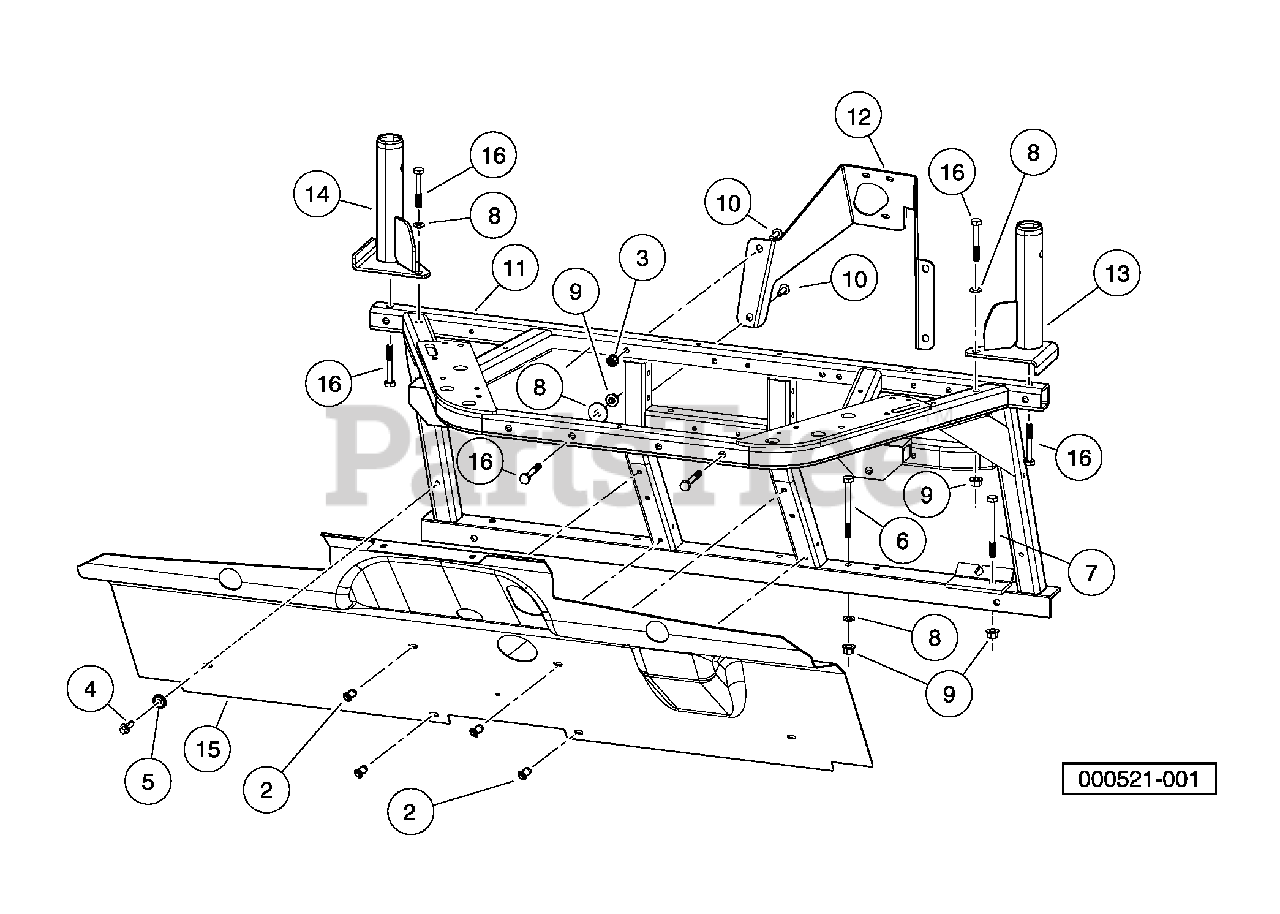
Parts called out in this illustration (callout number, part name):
1	Instl, Cowl Weldmnt/Splash Guard
2	Blind Rivet, Push Type
3	Nut,m8,all Metal Lock
4	M8-1.25x20 Taptite
5	Washer, Flat, 3/8, Blk Fin
6	BOLT, M10 X 100, ZN-NI/BLK
7	Bolt, M10 X 1.50 X 110 Black
8	Washer Hard,m10
9	Nut Flg M10 X 1.5 Mech Def
10	Bolt Flanged Head, M8 X 1.25 X 65
11	Weldment, Dash, Front
12	Bracket, Column, Steering
13	Weldment, Front, Base, ROPS, Right-Hand
14	Weldment, Front, Base, ROPS, Left-Hand
15	Guard, Splash, Gas Injection
16	Bolt, M10 X 1.50 X 65
